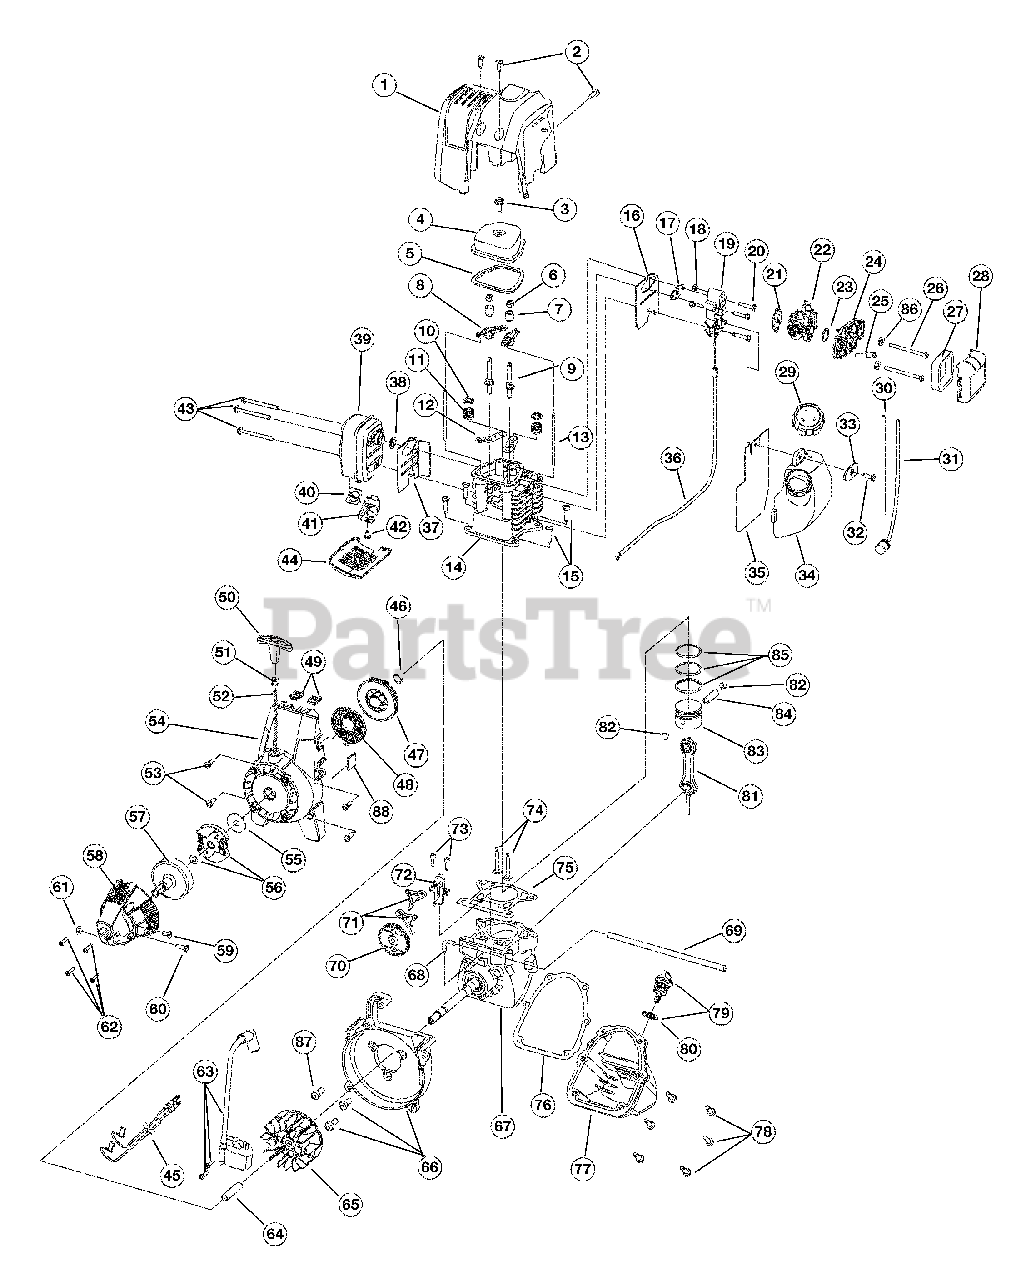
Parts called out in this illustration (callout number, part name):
1	Engine Cover
2	Engine Cover Screws
3	Valve Cover Screw
4	Valve Cover
5	Valve Cover Gasket
6	Rocker Adjustment Nut
7	Rocker Arm Pivot
9	Rocker Arm Stud
10	Valve Spring Retainer
11	Valve Spring
12	Push Rod Guide
13	Push Rod
14	Cylinder Head
15	Cylinder Screw
16	Intake Baffle
17	Carburetor Mount Gasket
18	Nut
19	Carburetor Mount
20	Carburetor Mount Screw
21	Carburetor Gasket
22	Carburetor with Primer
23	O-Ring, Carburetor
24	Air Filter/Choke Cover Assembly
25	Breather Tube
26	Air Filter Mounting Screw
28	Air Filter Cover
30	Fuel Return Line
31	Fuel Pick-Up Line with Filter
34	Fuel Tank Assembly
35	Fuel Tank Shield
36	Throttle Cable
37	Muffler Baffle
38	Muffler Gasket
39	Muffler
40	Spark Arrestor Screen
41	Screen Cover
43	Muffler Mounting Screw
44	Muffler Cover
45	Switch Wire Assembly
46	Palnut
47	Recoil Pulley
48	Recoil Spring
50	Pull Handle
53	Starter Housing Screw
54	Starter Housing Assembly
55	Clutch Washer
56	Clutch with Spacer
57	Clutch Drum
58	Clutch Cover
59	Anti-Rotation Screw
60	Screw
62	Clutch Cover Screws
63	Ignition Module with Screws
65	Flywheel
66	Shroud Assembly w/Screws
67	Crankcase Assembly
69	Breather Hose
71	Cam Follower Set
72	Cam Bracket
73	Cam Bracket Screw
74	Valves, Intake and Exhaust
75	Cylinder Gasket
76	Oil Pan Gasket
77	Oil Pan
78	Oil Pan Screws
79	Dipstick Assembly
81	Connecting Rod
82	Wrist Pin Button
83	Piston
85	Piston Ring Set
